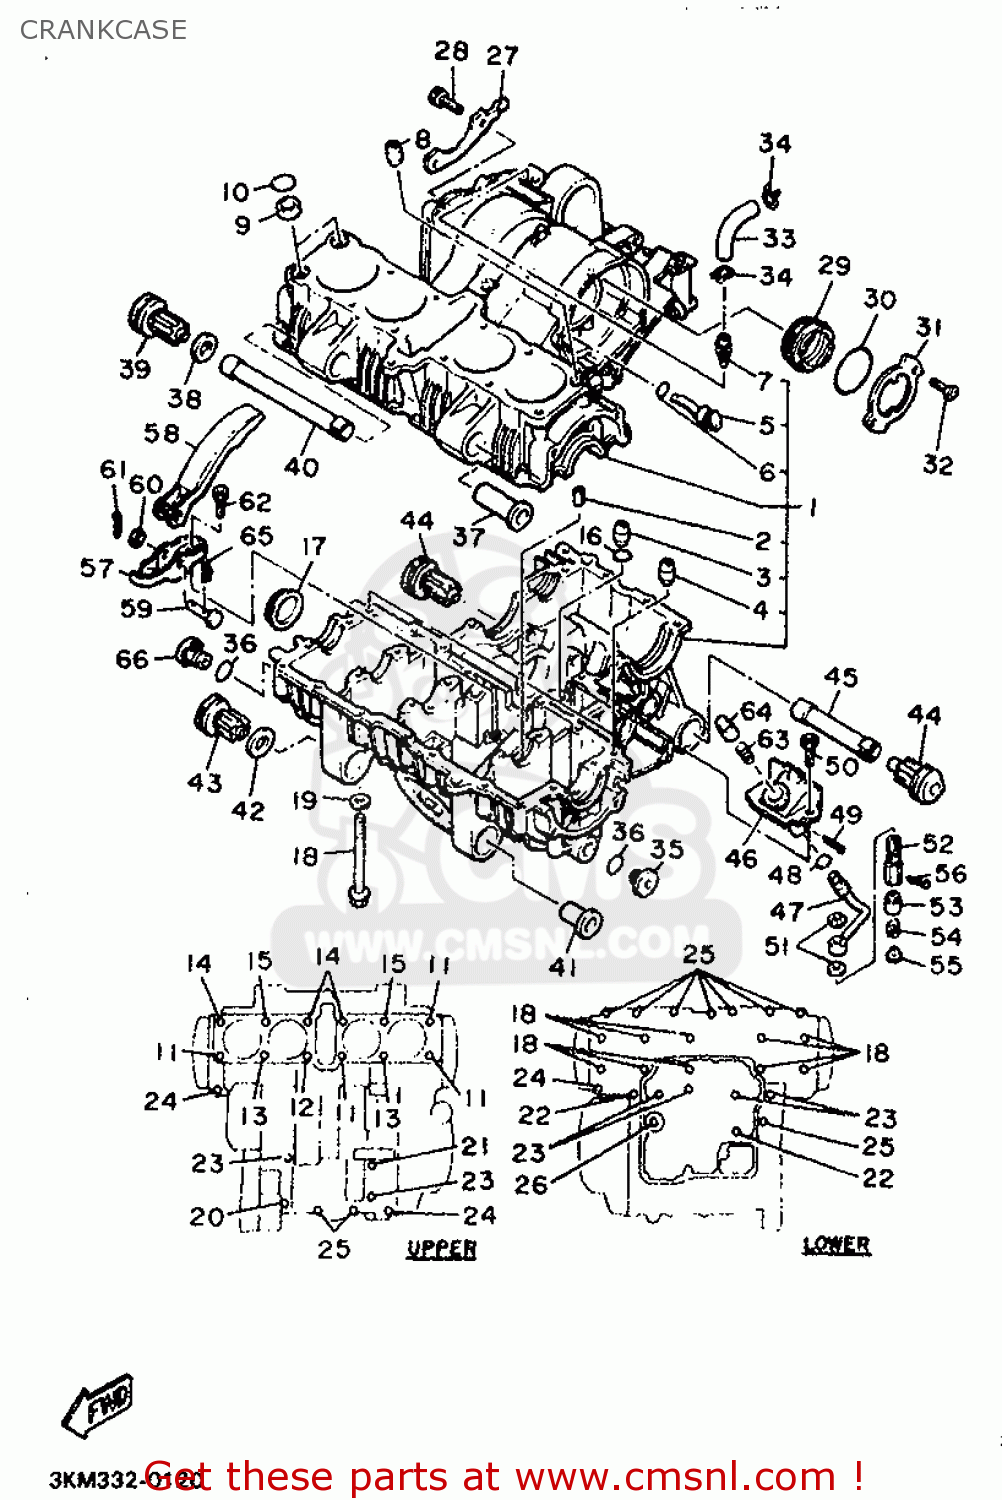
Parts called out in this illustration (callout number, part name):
01	CRANKCASE ASSY
02	NOZZLE 1
03	PIN, DOWEL
04	P1N, DOWEL
05	NOZZLE 2
06	O-RING (4G0)
07	PIPE, BREATHER 2
08	PIN, DOWEL
09	COLLAR (1L9)
10	O-RING (1L9)
11	BOLT, STUD (4G0)
12	BOLT, STUD (4G0)
13	BOLT, STUD (4G0)
14	BOLT, CYLINDER HOLDING 3
15	BOLT, CYLINDER HOLDING 4
16	O-RING (1J7)
17	PLUG (4H7)
18	BOLT, FLANGE (2K7)
19	WASHER, PLATE (33N)
20	BOLT, FLANGE (4G0)
21	BOLT, FLANGE (4G0)
22	BOLT, FLANGE (4G0)
23	BOLT, FLANGE (2H7)
24	BOLT, FLANGE (4A0)
25	BOLT, FLANGE (2H7)
26	BOLT, FLANGE (4H7)
27	PLATE, BEARING COVER
29	HOUSING, BEARING 1
30	O-RING (4U8)
31	PLATE, BEARING COVER
32	SCREW, COUNTERSUNK (4H7)
33	PIPE, BREATHER 1
34	CLIP (371)
35	PLUG
36	O-RING (25G)
37	DAMPER, ENGINE MOUNT 3
38	WASHER, PLATE
39	DAMPER, ENGINE MOUNT 3
40	SPACER, ENGINE MOUNT
41	DAMPER 4
42	WASHER, PLATE
43	DAMPER, ENGINE MOUNT 1
44	DAMPER, ENGINE MOUNT 2
45	SPACER, ENGINE MOUNT
46	SLEEVE TENSIONER ASSY
47	PIPE, DELIVERY 2
48	O-RING (11M)
49	PIN, COTTER
50	BOLT, HEXAGON SOCKET HEAD
51	GASKET 256131680000 (NAS)
52	BODY, RELIEF
53	PLUNGER, RELIEF
54	SPRING, COMPRESSION (4G0)
55	WASHER (4G0)
56	PIN, COTTER
57	BRACKET,TENSIONER
58	TENSIONER ARM COMP.
59	PIN, CLEVIS (4G0)
60	WASHER(526)
61	PIN,COTTER
62	BOLT, HEXAGON SOCKET HEAD
63	SPRING, COMPRESSION(46X)
64	PLUNGER, TENSIONER
65	CLIP (4G0)
66	PLUG
